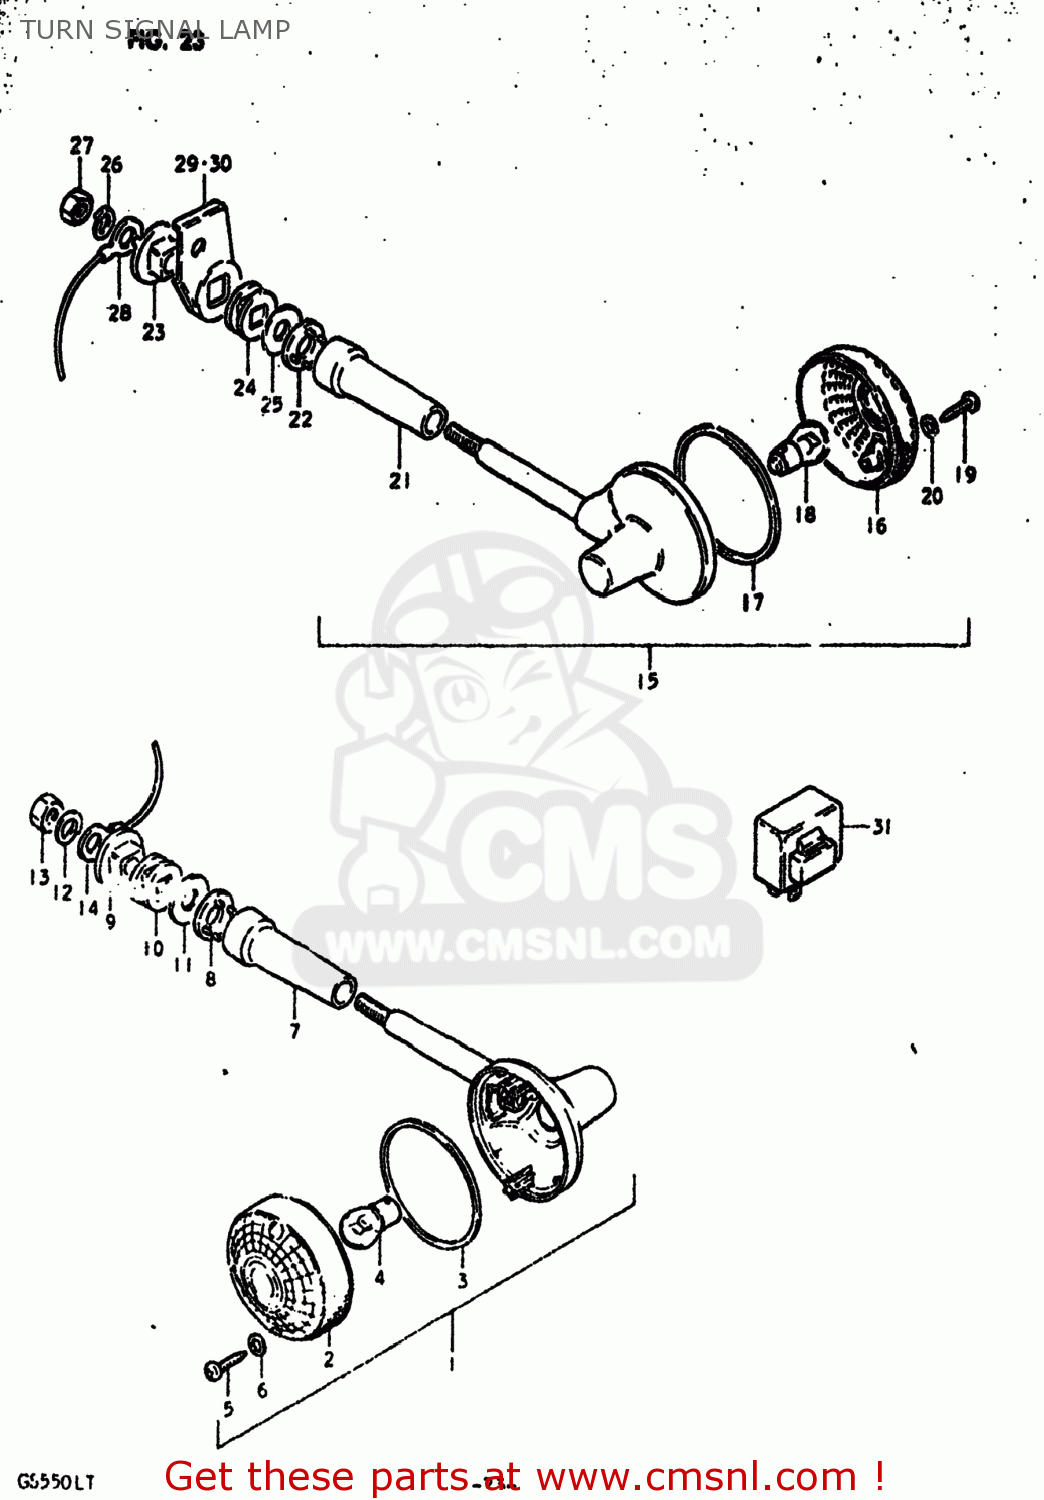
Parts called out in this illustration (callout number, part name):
1	LAMP ASSEMBLY,REAR TURN SIGNAL
2	LENS
3	GASKET (NAS)
4	BULB(12V23W,STANLEY,A4577A)
5	SCREW
6	GASKET (NAS)
7	COVER,STAY
8	SPACER
9	SPACER,TURN SIGNAL LAMP
10	CUSHION
11	WASHER (10.5X30X2.3)
12	LOCK WASHER
13	NUT
14	WIRE
15	LAMP ASSEMBLY,REAR TURN SIGNAL
16	LENS
17	GASKET (NAS)
18	BULB(12V23W,STANLEY,A4577A)
19	SCREW
20	GASKET (NAS)
21	COVER,STAY
22	SPACER
23	SPACER,TURN SIGNAL LAMP
24	CUSHION
25	WASHER (10.5X30X2.3)
26	LOCK WASHER
27	NUT
28	WIRE,REAR TURN SIGNAL EA
29	BRACKET,RR TURNSIGNAL LAMP,R
30	BRACKET,RR TURNSIGNAL LAMP,L
31	RELAY,TURN SIGNAL
